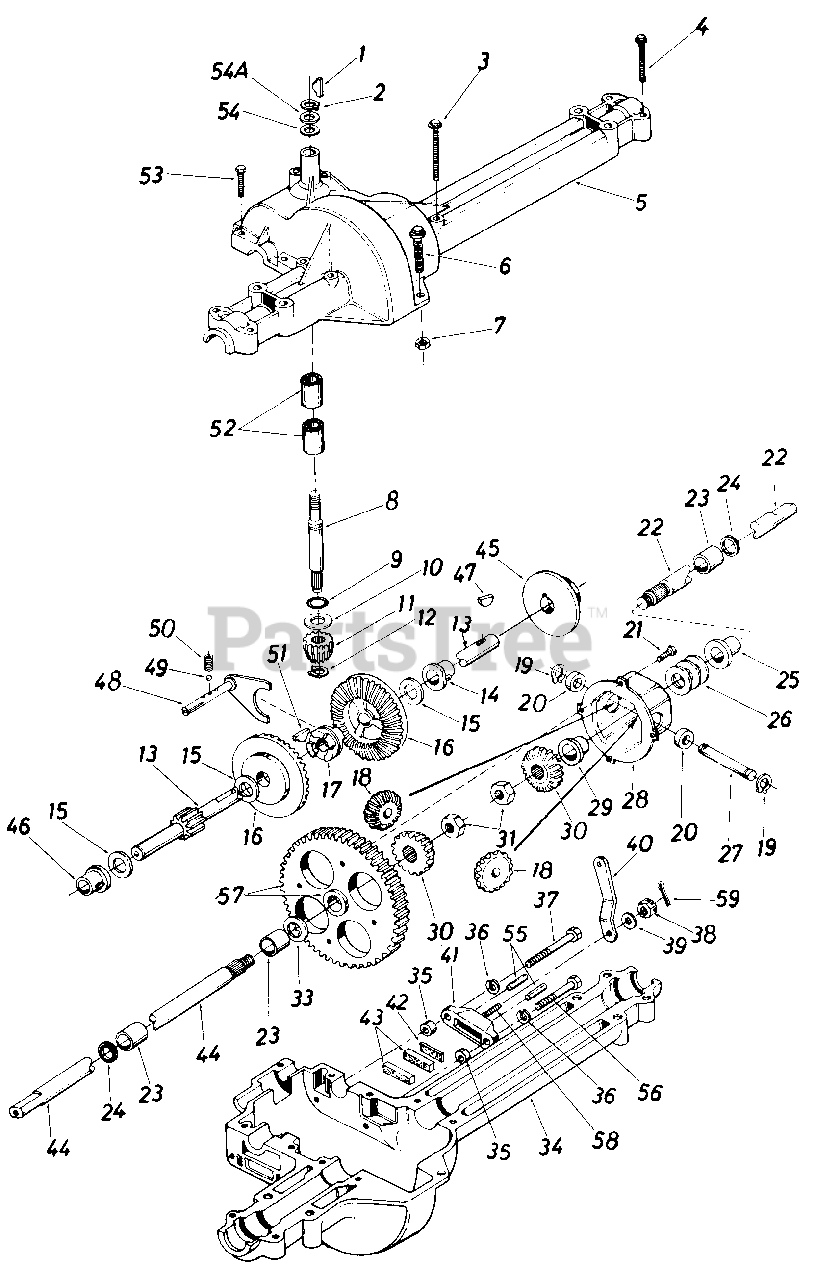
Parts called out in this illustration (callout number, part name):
1	#4 Hi-Pro Key 3/32 x 5/8" Dia.
2	Snap Ring .625" Shaft
3	Hex Bolt 1/4-20 x 1.75" Lg.*
4	Hex Bolt 1/4-20 x 1.25" Lg.*
5	Upper Housing
6	Hex Fl-Bolt 1/4-20 x .88" Lg.*
7	Hex Nut 1/4-20 Thd.*
8	Input Shaft
9	Square Seal 5/8" I.D.
10	Thrust Washer 5/8" I.D. x 1.25" O.D
11	Pinion Input 14T
12	Retaining Ring 7/16" Ext.
13	Drive Shaft R.H.
14	Flange Brg. 5/8" I.D. x 3/4" Lg.*
15	Fl-Wash. 5/8" I.D. x 1.0" O.D. x .020 Thk.
15	Fl-Wash. 5/8" I.D. x 1.0" O.D. x .030 Thk.
15	Fl-Wash. 5/8" I.D. x 1.0" O.D> x .040 Thk.
16	Bevel Gear 42T
17	Clutch Collar
18	Miter Gear 15T
19	Snap Ring
20	Thrust Bearing 1/2" I.D. x 1.0" O.D.
21	Pan Head Scr. 1/4-20 x .50" Lg. w/ Patch
22	Axle R.H.
23	Sleeve Bearing 3/4" I.D. x 1.0" Lg.
24	Oil Seal 3/4" I.D.
25	Flange Bearing 3/4" I.D. x 15/16" Lg.
26	Fl-Wash. .760" I.D. x 1.49" O.D.
27	Cross Shaft
28	Differential Housing Ass'y.
30	Miter Gear
31	Hex Ins. L-Nut 1/2-20 Thd.
33	Fl-Wash. .760" I.D. x 1.49" O.D.
34	Lower Housing
35	Spacer .53" O.D. x 3/8" Lg.
36	L-Wash. 1/4" I.D.*
37	Hex Bolt 1/4-20 x 1.50" Lg. (Grade 5)
38	Castle Nut 5/16-24 Thd.*
39	Fl-Wash. .344" I.D. x .875" O.D.
40	Actuating Arm R.H.
41	Brake Yoke
42	Puck Plate
43	Brake Puck
44	Axle L.H.
45	Brake Disc
46	Flange Bearing 5/8" I.D. x 15/16" Lg.
47	Woodruff Key 3/16 x 5/8 HT
48	Shift Fork Ass'y.
49	Ball Detent.250" Dia.
50	Spring Detent
51	#9 Hi-Pro Key 3/16" x 3/4" Dia. HT
52	Needle Brg. 5/8" I.D. x 1/2" Lg.
53	Hex Bolt 1/4-20 x 1.00" Lg.
54	Fl-Wash. 5/8" I.D. x .030
54A	Fl-Wash. 5/8" I.D. x .040
55	Actuating Pin 5/16" Dia.
56	Hex Bolt 1/4-20 x 1.50" Lg. (Grade 5)
57	Differential Gear 72T Ass'y w/ Bearing
58	Sq. Hd. Bolt 5/16-24 Thd.
59	Cotter Pin 3/32" Dia. x .50" Lg.
